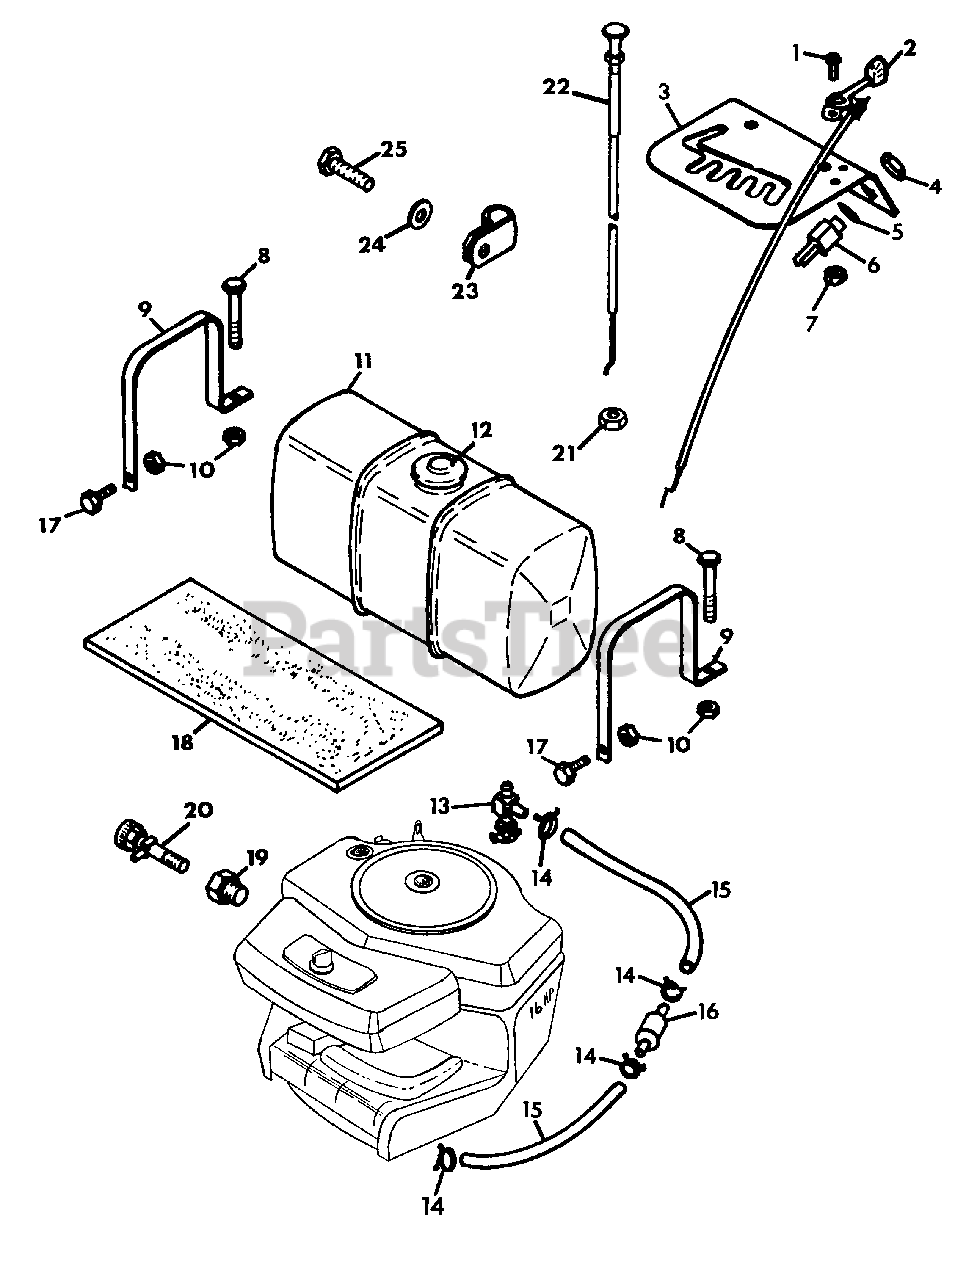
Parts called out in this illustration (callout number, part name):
1	SCREW, MACH. 10-24X.50
2	LEVER, CONTROL
3	PLATE, INSTRUCTION
4	NUT, JAM 9/16-24
5	WASHER, LOCK
6	SWITCH, IGNITION
7	NUT, LOCK 10-24
8	BOLT, HEX 1/4-20X2.75
9	STRAP, FUEL TANK
10	NUT, LOCK 1/4-20
11	TANK, FUEL (12 QTS.)
12	CAP, FUEL TANK
13	VALVE AND STRAINER
14	CLAMP, FUEL HOSE
15	HOSE, FUEL
16	FILTER, FUEL
17	BOLT, HEX 1/4-20X.625
18	PAD, FUEL TANK
19	ADAPTOR, OIL DRAIN
20	COCK, OIL DRAIN
21	NUT, JAM 3/8-24 HEX HEAD
22	CONTROL, CHOKE
23	CLAMP
24	WASHER, FLAT .281X.625X.065
25	BOLT, HEX 1/4-20X1.00
